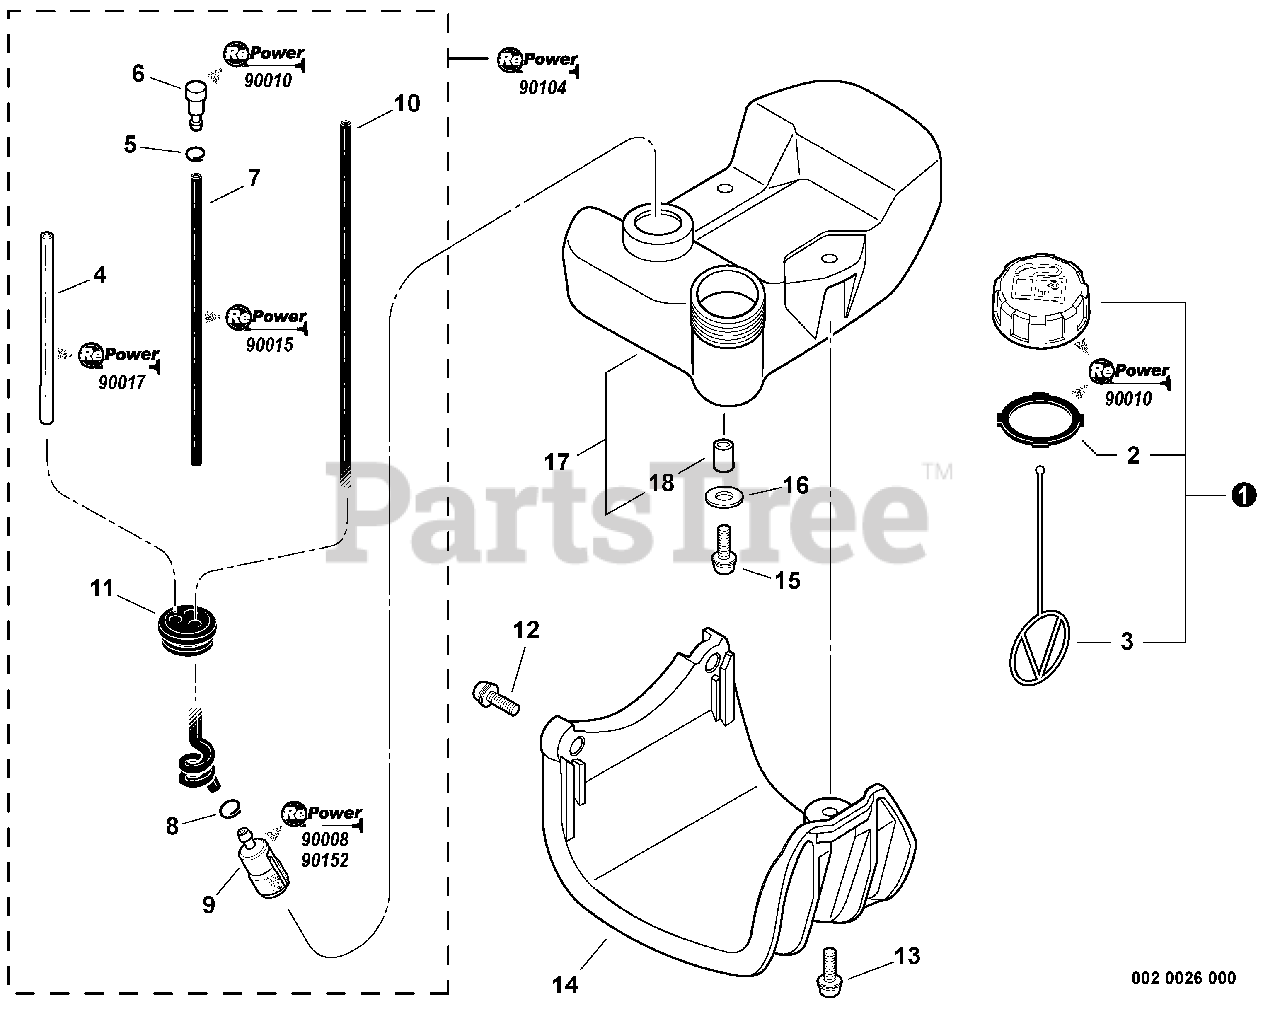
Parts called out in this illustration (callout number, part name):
1	CAP ASSY - ORANGE
2	GASKET, CAP
3	CONNECTOR, CAP
4	PIPE - 3X6X80 -- CLEAR
5	CLIP - 6.5
6	VENT, FUEL TANK
7	PIPE - 3X6X115 -- BLACK
8	CLIP - 6.5
9	FILTER, FUEL
10	PIPE, FUEL - SPIRAL
11	GROMMET
12	SCREW - 5X22
13	SCREW - 5X20
14	GUARD, FUEL TANK
15	SCREW - 5X16
16	WASHER - 5
17	FUEL TANK ASSY
19	RePower FUEL SYSTEM KIT
20	RePower TUNE-UP KIT
21	RePower FILTER KIT
22	Repower CAP AND VENT KIT
23	RePower BULK PIPE - 25 FEET
24	RePower BULK PIPE - 25 FEET
